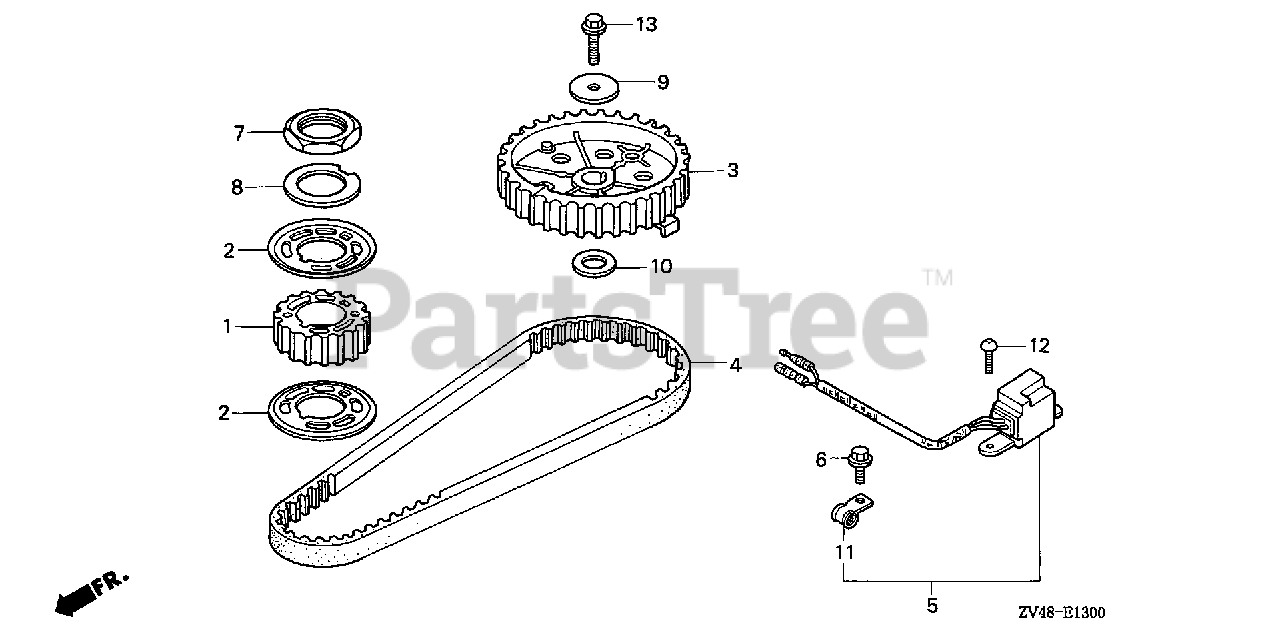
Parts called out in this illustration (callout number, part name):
1	PULLEY, TIMING
2	FLANGE, TIMING PULLEY
3	PULLEY, CAMSHAFT
4	BELT, TIMING
5	COIL ASSY., PULSER
6	BOLT, FLANGE (6X12)
6	BOLT, FLANGE (6X12) (CT200)
7	NUT, LOCK (27MM)
8	WASHER, LOCK (27MM)
9	WASHER, PLAIN (6MM)
10	WASHER, PLAIN (13MM)
11	CLIP, CORD
12	SCREW, PAN (5X14)
13	BOLT, FLANGE (6X18)
